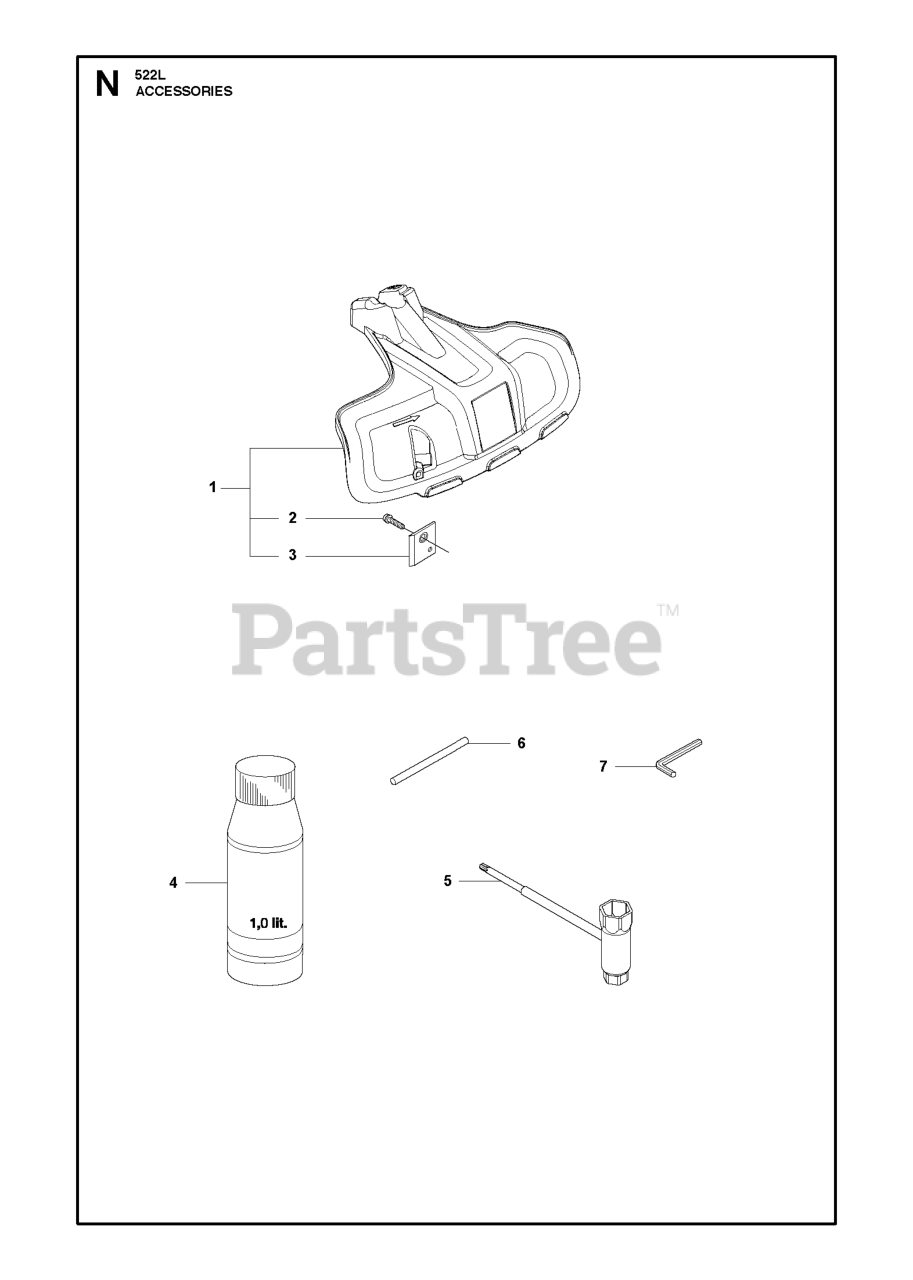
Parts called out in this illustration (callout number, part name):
1	TRIMMER GUARD 323L MFL.
2	SCREW ITXSCFT PW4.8X16 T27 CH
2	SCREW
3	LINE CUTTER
5	COMBINATION WRENCH TORX
6	LOCKING PIN
